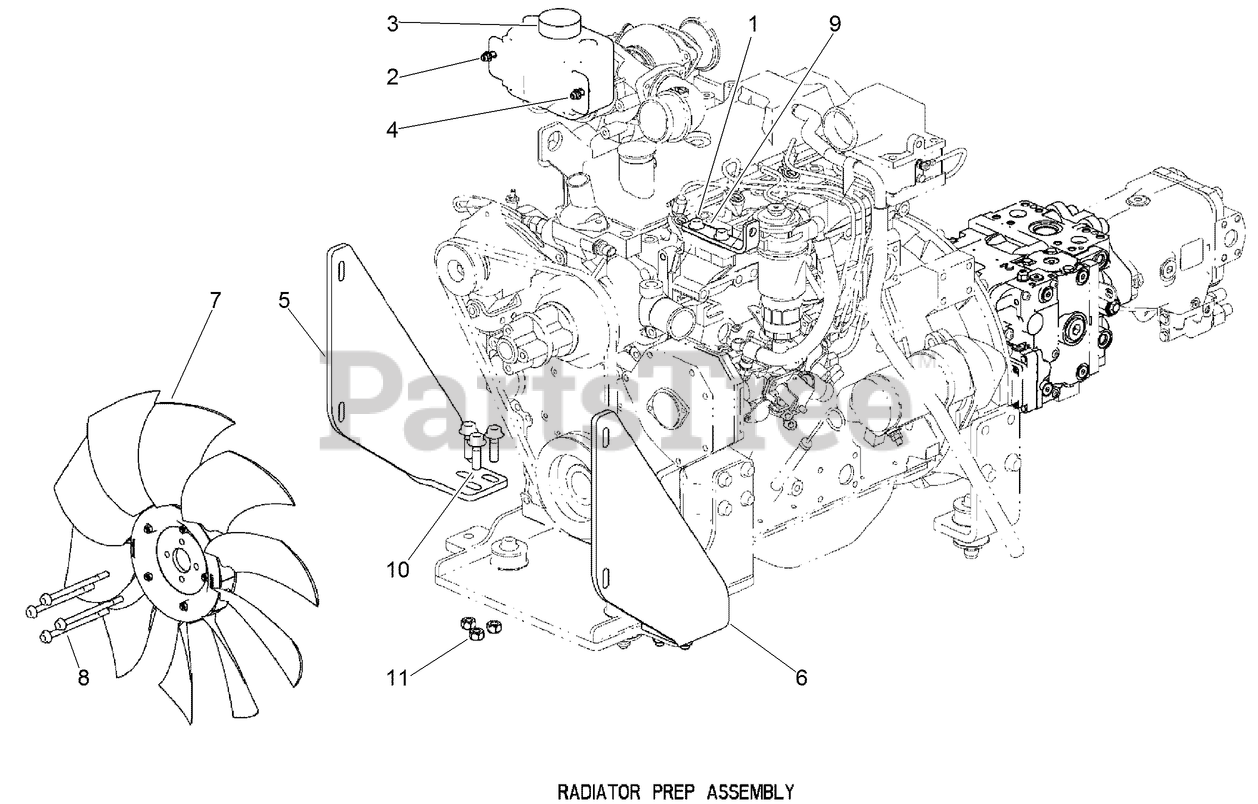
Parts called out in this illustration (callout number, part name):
1	SCREW-FLANGE
2	NUT, METRIC FLANGE PREVAILING - M6 Zinc
3	TANK-Overflow
4	SCREW, METRIC FLANGE w/BODY-M6 x 25
5	BRACKET - Radiator Mounting
6	BRACKET - Radiator Mounting
7	FAN-19 INCH (10-BLADE)
8	SCREW-FLANGE, METRIC
9	PLATE - Radiator Strap Mount
